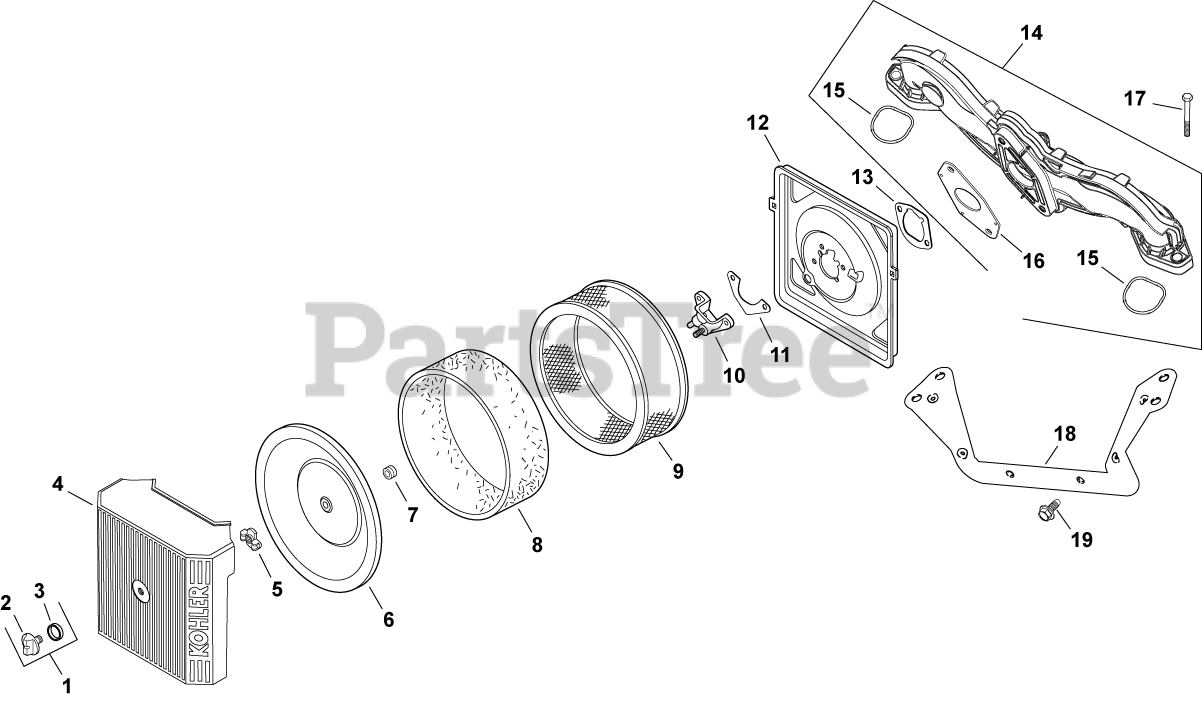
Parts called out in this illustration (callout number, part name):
1	KIT, KNOB W/SEAL
2	KNOB, COVER
4	COVER, AIR CLEANER
5	NUT, WING
6	COVER, INNER AIR CLEANER
7	SEAL, INNER AIR CLEANER
8	ELEMENT, PRECLEANER (LOW)
9	ELEMENT, AIR CLEANER - Also available Retail Packaged 47 883 03-S1 Air Filter Kit
10	CUP, SPIT-BACK W/STUD
11	GASKET, FUEL SPITBACK CUP
12	BASE, AIR CLEANER-USE 24 094 87-S
13	GASKET, AIR CLEANER BASE
14	MANIFOLD, INTAKE - PLASTIC-USE 24 164 91
15	O-RING, INTAKE PORT
16	GASKET, CARBURETOR
17	SCREW, FLG M6X1.0X40
18	BRACKET, AIR CLEANER BASE
19	SCREW, FLG THD FRM M5X.8X10
